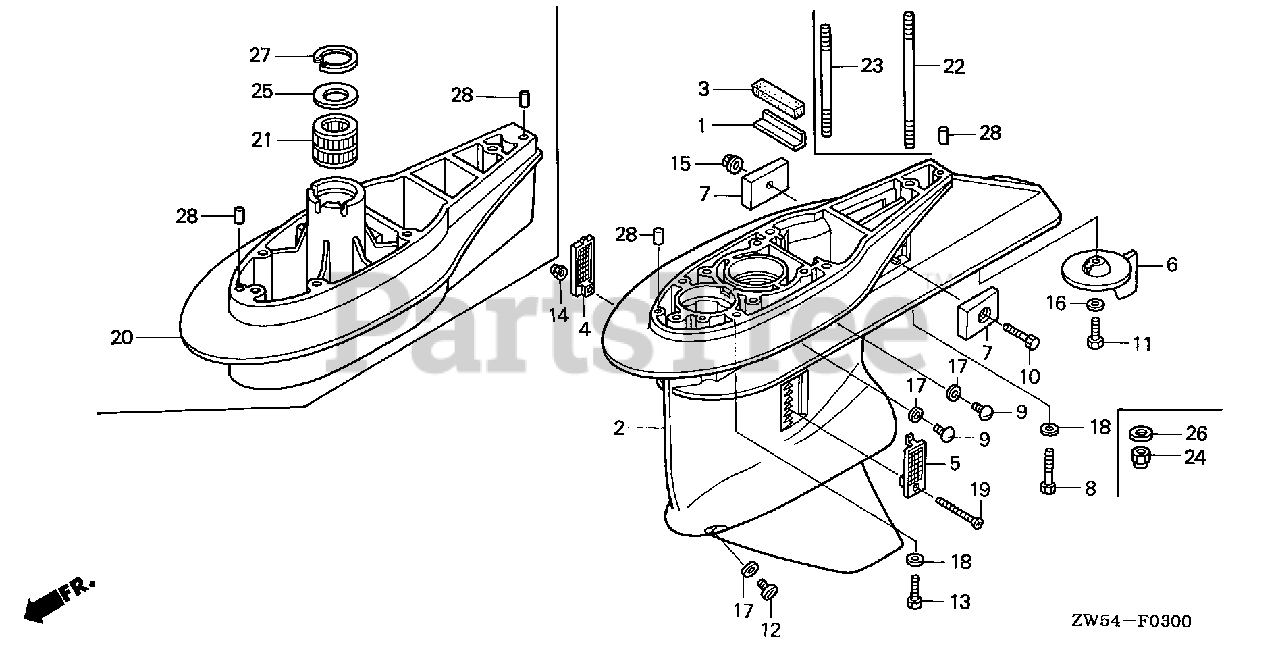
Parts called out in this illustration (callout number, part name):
1	PLATE, RUBBER SETTING
2	CASE, GEAR *NH282MU* (OYSTER SILVER METALLIC-U) (NOT AVAILABLE)
2	CASE, GEAR *NH282MU* (OYSTER SILVER METALLIC-U)
2	CASE, GEAR *NH282MU* (OYSTER SILVER METALLIC-U) (NA USE ALT:41101-ZW1-B05ZA)
3	GROMMET, GEAR CASE
4	SCREEN, R. WATER
5	SCREEN, L. WATER
6	TAB, TRIM *NH282MU* (OYSTER SILVER METALLIC-U)
7	METAL, ANODE
8	BOLT, HEX. (10X80)
9	BOLT, OIL CHECK (8X8)
10	BOLT, HEX. (6X32)
11	BOLT, HEX. (8X25)
12	BOLT, DRAIN PLUG (8MM)
13	BOLT, HEX. (10X40)
14	NUT, SELF-LOCK (5MM)
15	NUT, SELF-LOCK (6MM)
16	WASHER, PLAIN (8MM)
17	WASHER, NYLON (8MM)
18	WASHER, PLAIN (10MM)
19	SCREW, OVAL (5X45)
28	PIN, DOWEL (6X10)
